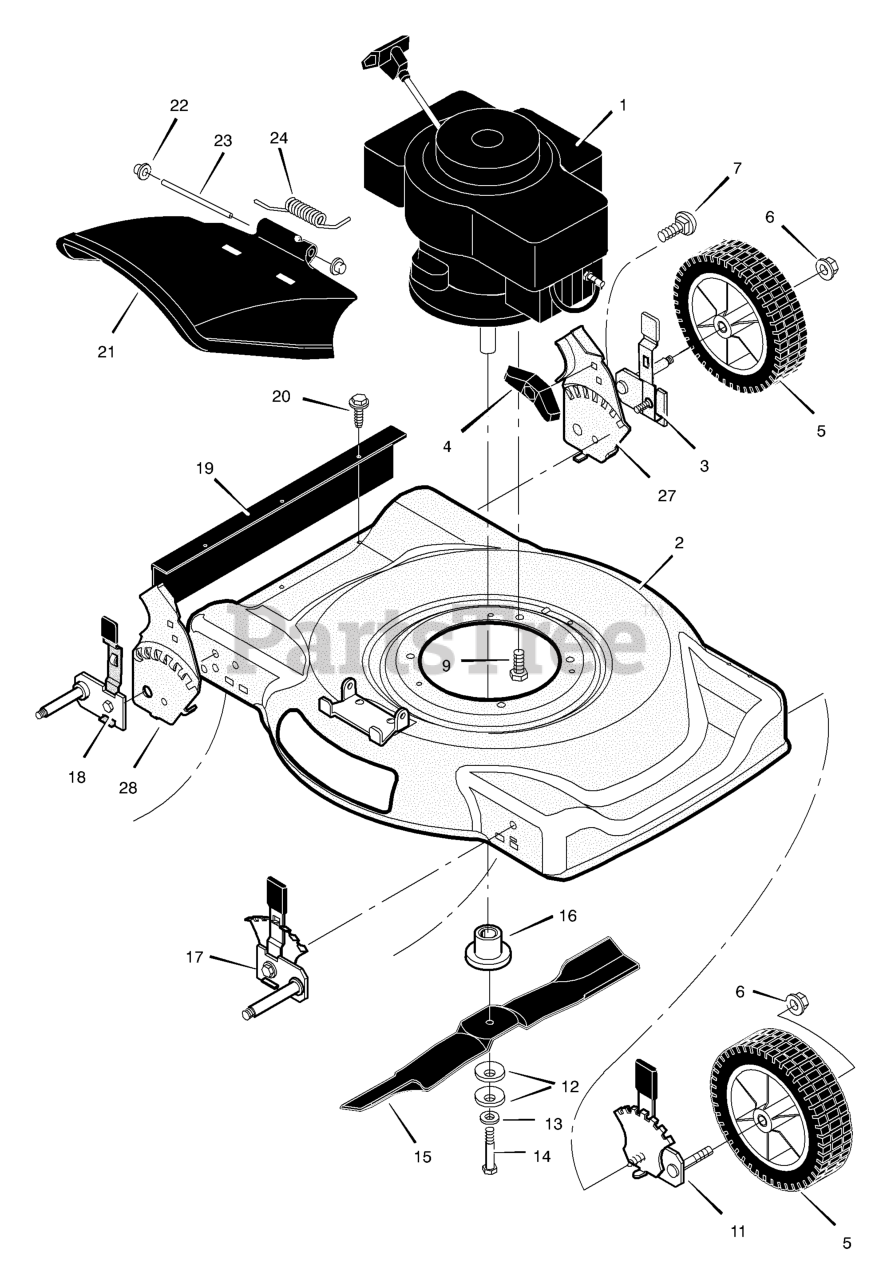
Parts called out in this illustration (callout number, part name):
1	Engine *
2	Housing
3	Height Adjuster, Left Rear (7" Wheels)
5	Wheel and Tire
6	Locknut, Flange
7	Bolt, Carriage
9	Bolt, Engine
10	Nut
11	Height Adjuster, Left Front (7" Wheels)
12	Washer, Belleville
14	Bolt, Hex
15	Blade, Side Discharge
16	Adapter, Blade
17	Height Adjuster, Right Front (7" Wheels)
18	Height Adjuster, Right Rear (7" Wheels)
19	Guard, Rear
21	Deflector, Chute
22	Push-On Cap
23	Pin, Pivot
27	Bracket, Left Handle
28	Bracket, Right Handle
